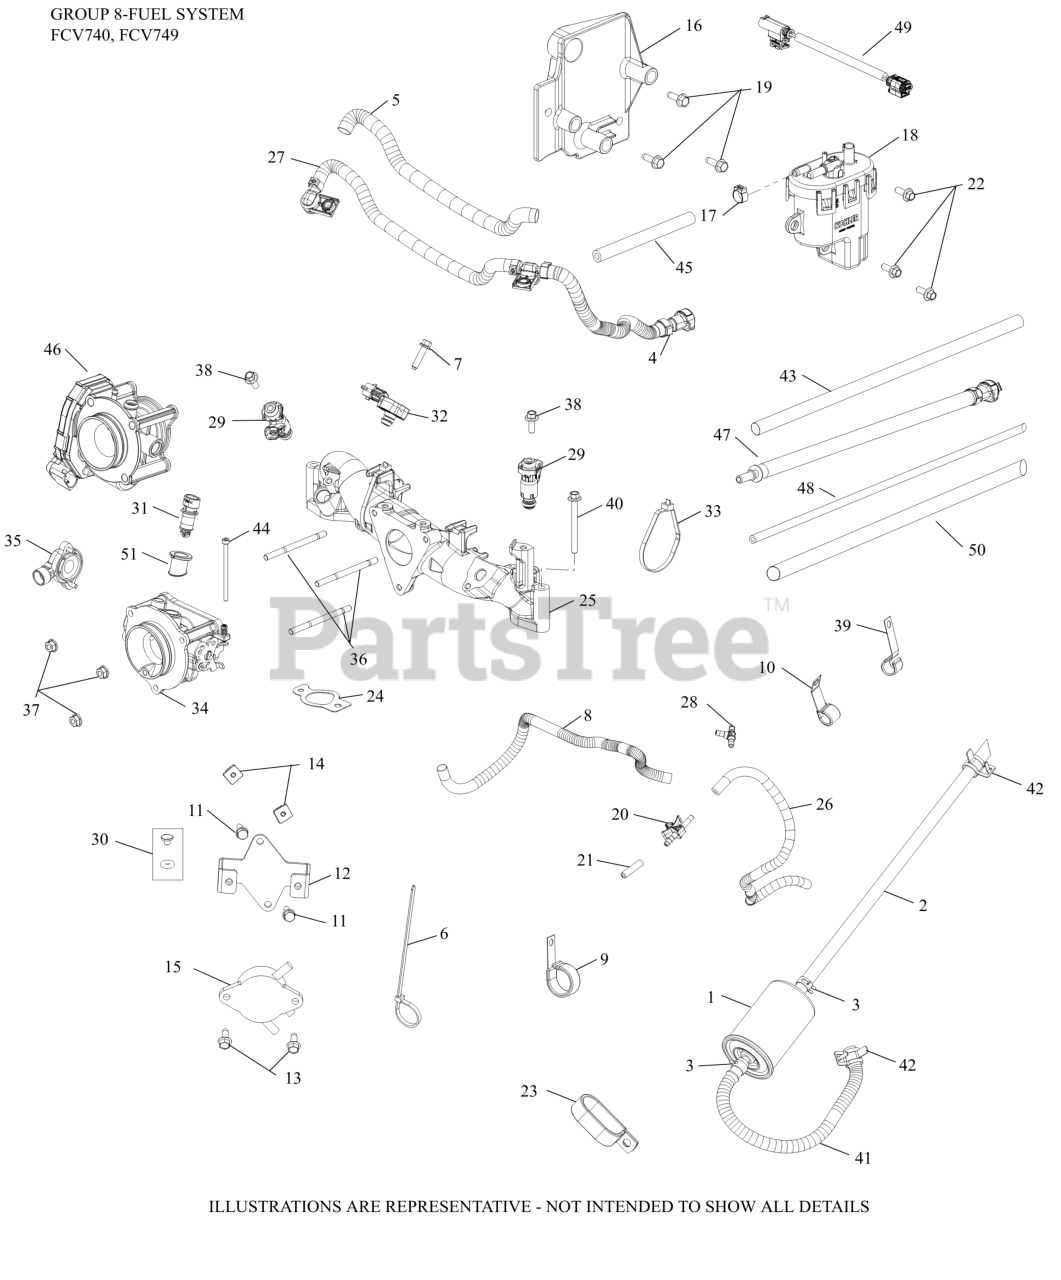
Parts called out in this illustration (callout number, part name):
1	FILTER, FUEL
2	HOSE, FUEL LOW PERM
3	CLAMP, BAND SPRING HOSE-(#2523737S)
3	SPRING CLAMP, HOSE
4	CLAMP, HOSE
5	SLEEVE, FUEL LINE
8	SLEEVE, ANTI-ABRASION
9	CLIP, CABLE
10	CLIP, CABLE
11	SCREW, TAP M6X1.7X18
12	BRACKET, FUEL PUMP MOUNTING
13	SCREW, THREAD FORMING
14	NUT, PLASTIC - BLACK
15	PUMP, PULSE FLEX FUEL
16	KIT,BAFFLE, FUEL MODULE
17	CLAMP, OETIKER
18	PUMP, FUEL MODULE
19	SCREW, THREAD FORMING
20	CONNECTOR, EVAPORATIVE
21	CAP, MASKING
22	SCREW, FLG M6X1.0X16
23	CLAMP, INSULATED DOUBLE
24	GASKET, INTAKE MANIFOLD-USE 24 041 79-S
25	KIT, MANIFOLD
26	HOSE, EVAPORATIVE (15.0)
27	FUEL HOSE ASSY (STRAIGHT FITTING)
27	FUEL HOSE ASSY (90? FITTING)
28	TEE CONNECTOR
29	INJECTOR, FUEL
30	KIT, FUEL INJECTOR O-RING
31	SENSOR, AIR TEMPERATURE
32	SENSOR, MAP
34	KIT, THROTTLE BODY ASSEMBLY
35	SENSOR, THROTTLE POSITION
36	STUD,M6X1.0X84
37	NUT, FLG M6X1.0
38	SCREW, FLG M6X1.0X16
39	CLIP, CABLE
40	SCREW, FLG M6X1.0X60
41	HOSE,LW PERM.FUEL 24.00"-USE 25 111 81-S
42	CLAMP, OIL COOLER HOSE-USE 25 237 31-S
42	CLAMP, HOSE (KM)-USE 25 237 31-S
42	CLAMP, HOSE
43	SLEEVE, ANTI ABRASION
